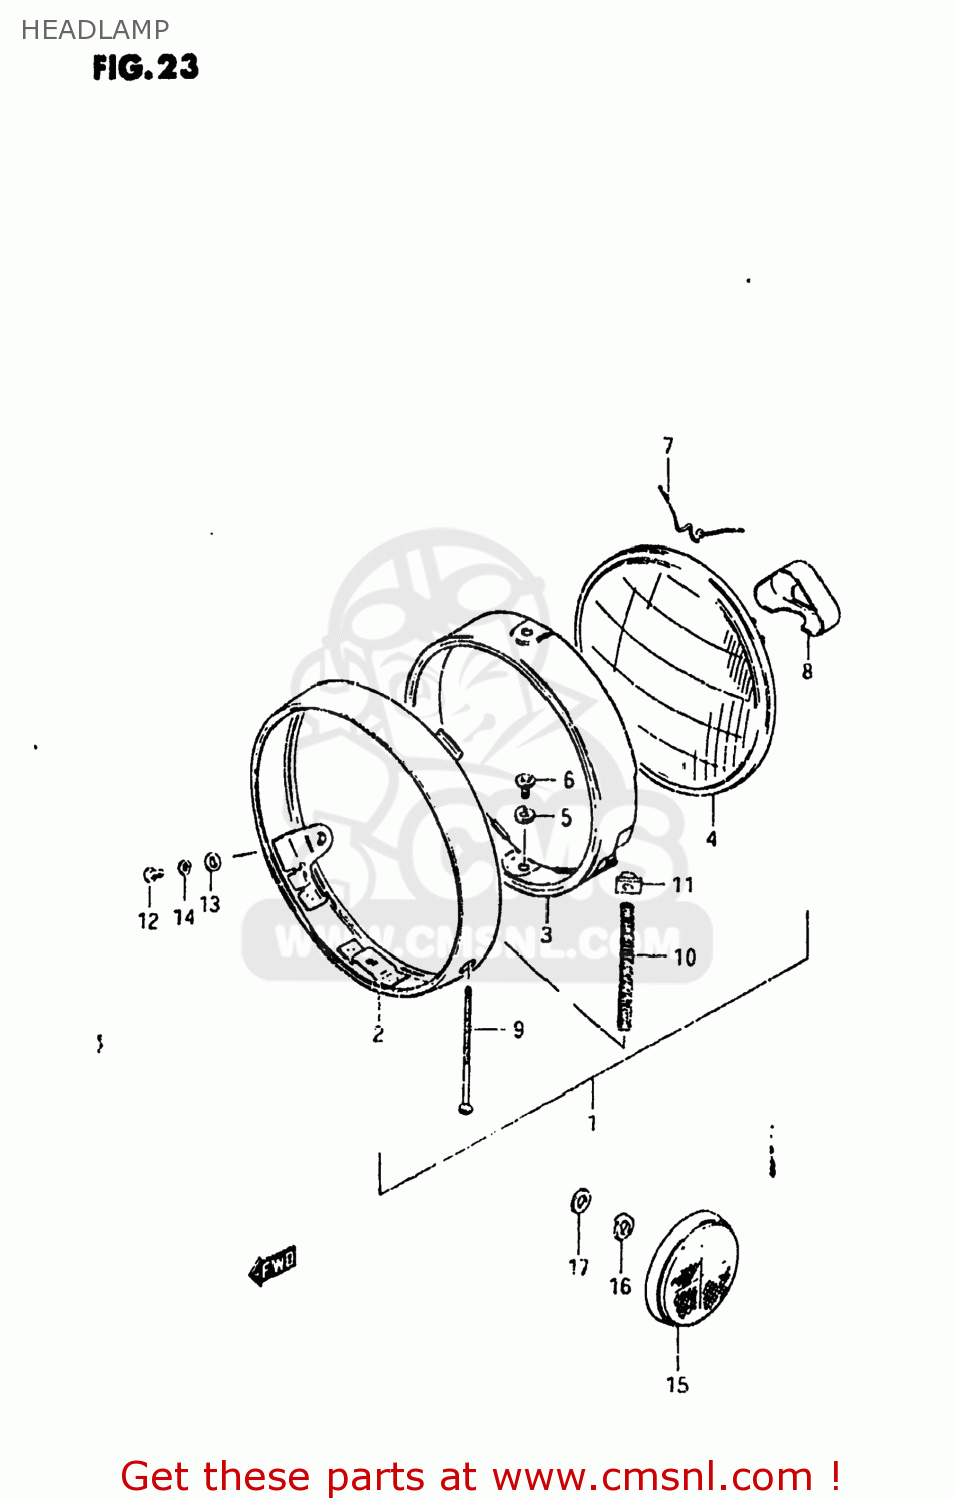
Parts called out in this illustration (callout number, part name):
1	HEADLAMP ASSEMBLY
2	RIM,HEADLAMP
3	RETAINER
4	LAMP UNIT
5	LOCK WASHER
6	SCREW
7	SPRING,HEAD LAMP UNIT
8	COVER
9	SCREW
10	SPRING
11	NUT
12	SCREW
13	WASHER
14	LOCK WASHER
15	REFLEX REFLECTOR,FR
16	LOCK WASHER
17	WASHER
